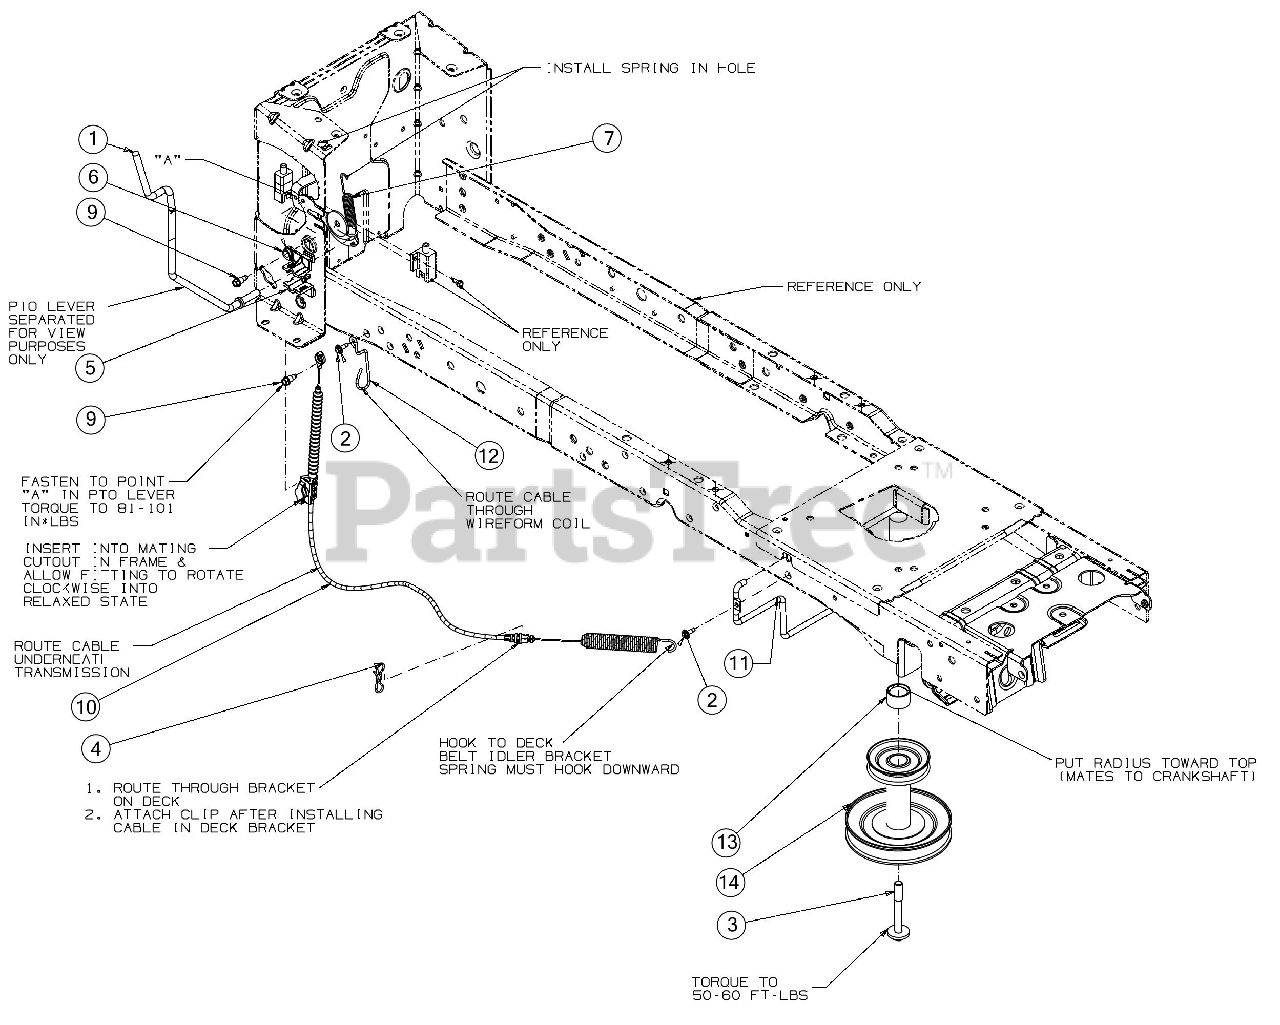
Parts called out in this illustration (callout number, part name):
1	PTO HANDLE ASSEMBLY
2	SCREW M6-1 X .625
3	SCREW 7/16-20 X 3.50
4	BOW TIE COTTER PIN
5	PTO HANDLE BOTTOM BEARING
6	PTO HANDLE TOP BEARING
7	EXTENSION SPRING
9	SHOULDER SCREW
10	PTO HANDLE CABLE
11	BELT KEEPER ROD
12	CABLE GUIDE WIRE
13	ENGINE PULLEY SPACER
14	ENGINE PULLEY
